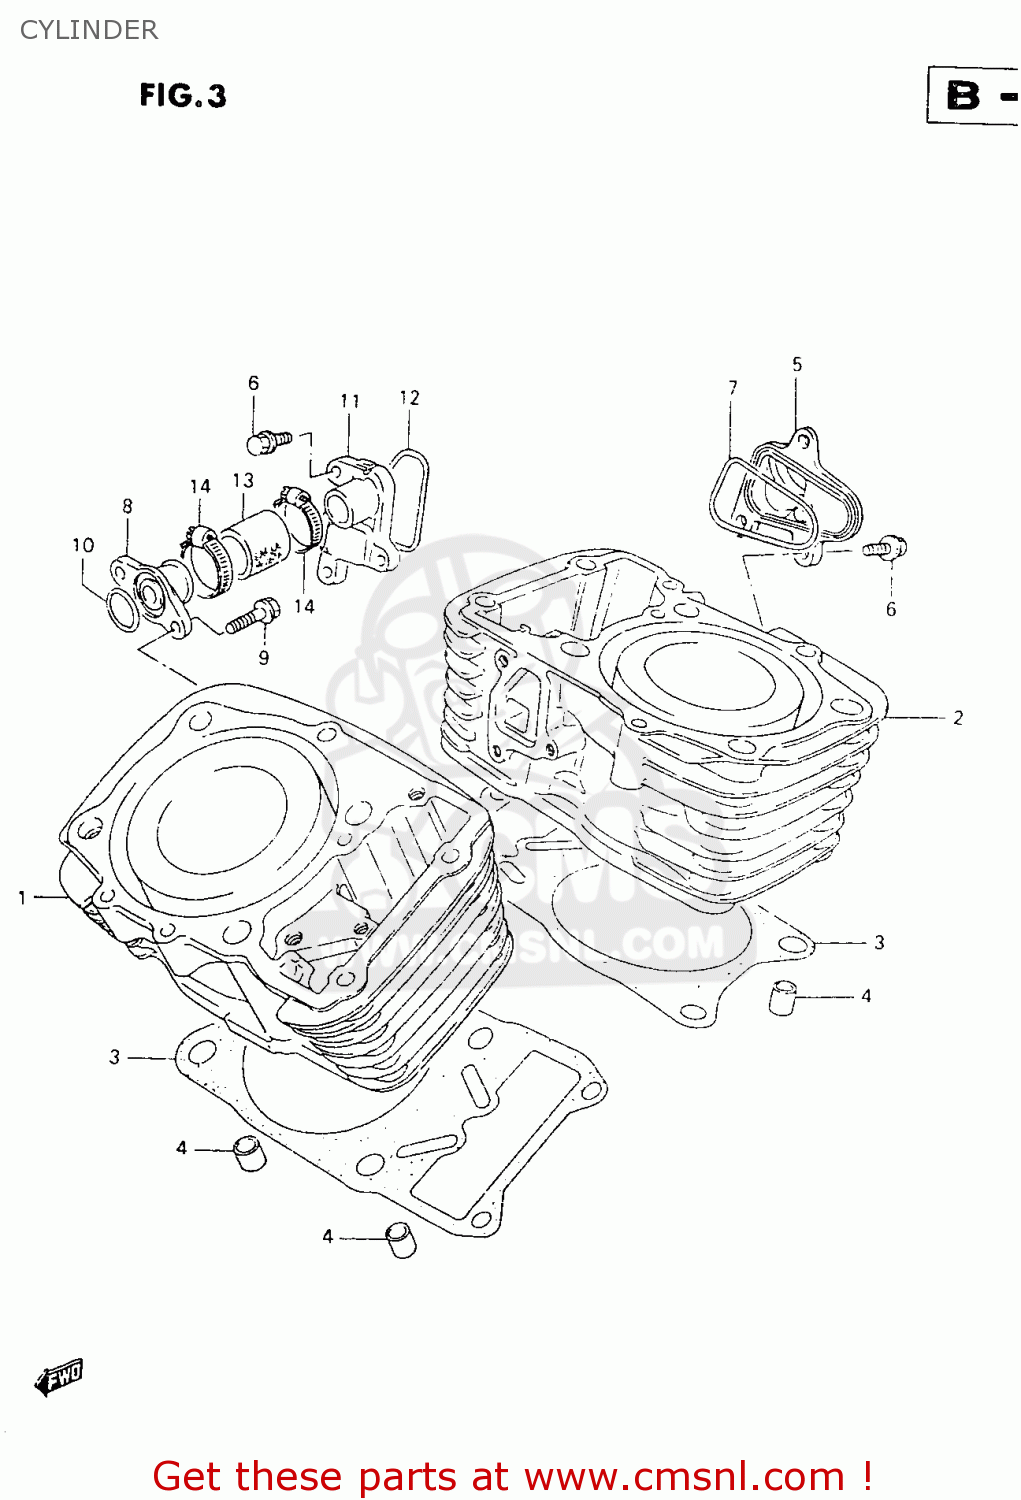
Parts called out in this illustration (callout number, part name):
1	CYLINDER COMP,FRONT
2	CYLINDER COMP,REAR
3	GASKET,CYLINDER
4	PIN
5	CHAMBER,WATER INLET
6	BOLT
7	O RING,INLET WATER CHAMBER
8	UNION,WATER INLET
9	BOLT
10	O RING(D:2.4,ID:15.8)
11	CHAMBER,WATER OUTLET
12	O RING,OUTLET WATER CHAMBER
13	HOSE,RADIATOR INLET
14	CLAMP
